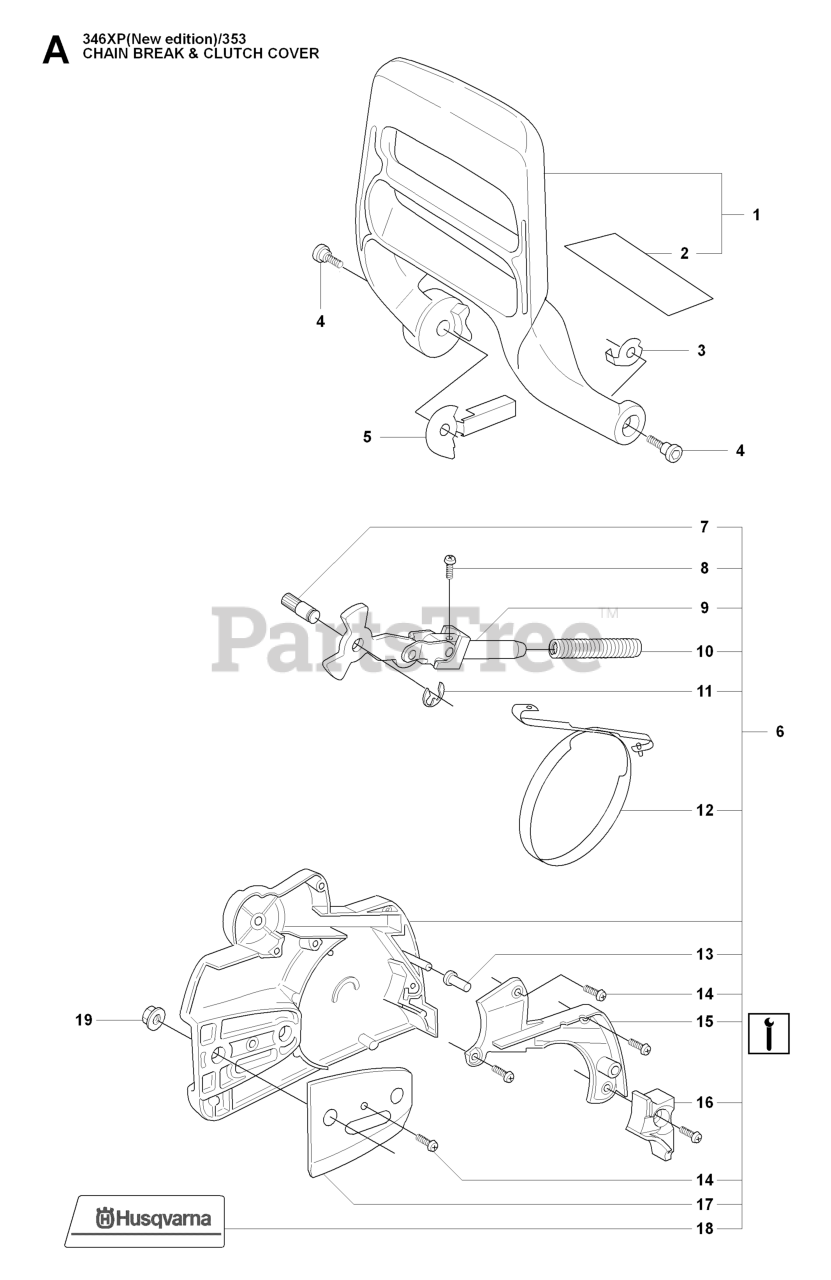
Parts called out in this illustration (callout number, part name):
1	CHAINBRAKE HANDLE
2	PROTECTOR
6	CHAIN BRAKE
6	CHAIN BRAKE SILVER
12	BRAKE BAND
19	NUT M8 FLANGE
